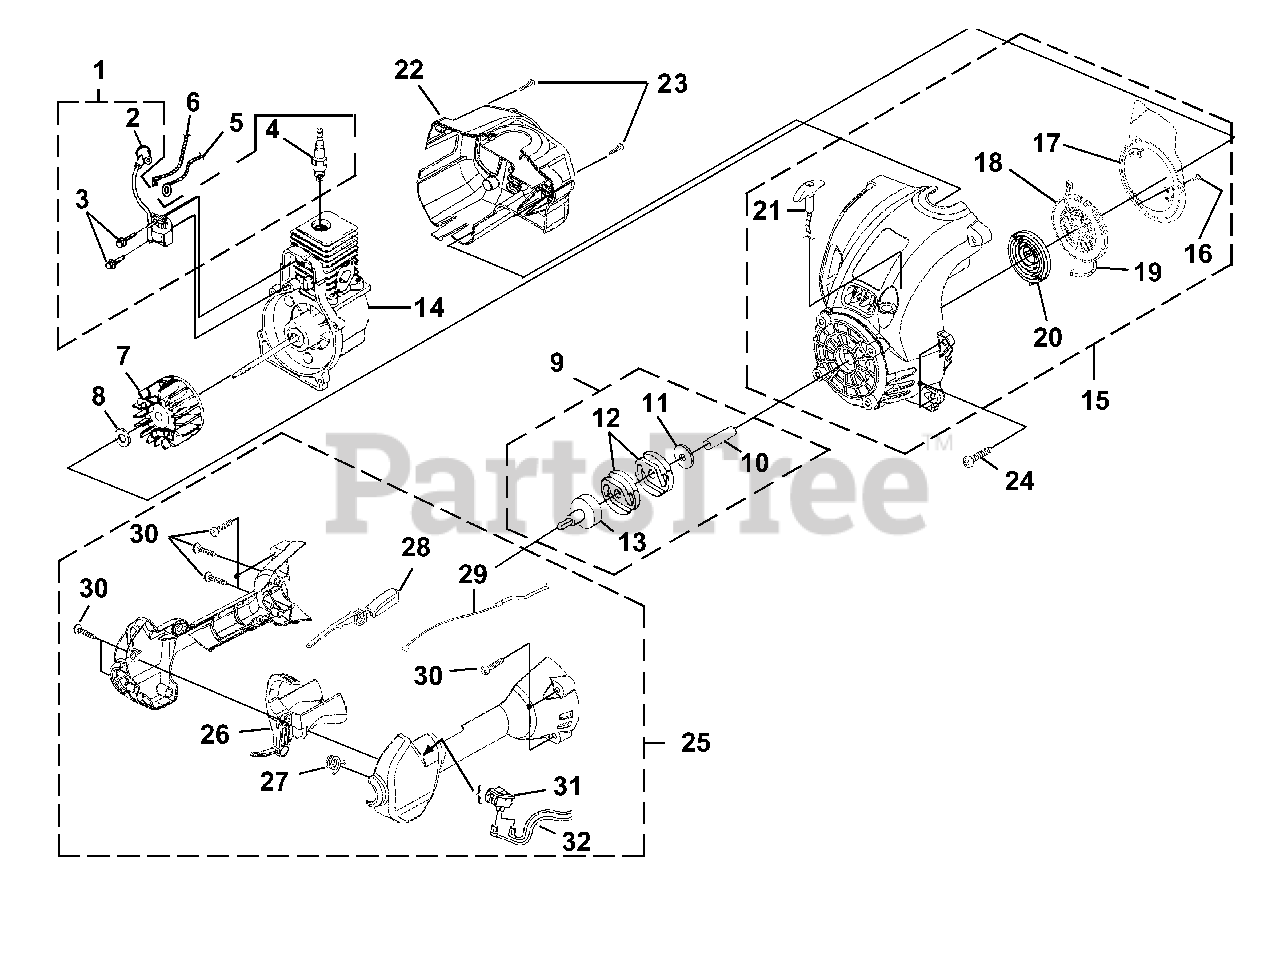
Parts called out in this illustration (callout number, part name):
1	IGNITION KIT
2	TERMINAL & COVER
3	SCREW-Taptite (8-32 X 1")
4	SPARK PLUG
5	LEAD-Electrical
6	LEAD-Electrical
7	ROTOR KIT
8	WASHER-Flat
9	CLUTCH AND DRUM KIT
10	SPACER
11	WASHER-Flat
12	CLUTCH
13	CONNECTOR AND DRUM
14	SHORT BLOCK
15	COMPLETE STARTER ASSEMBLY
16	SCREW-Thread Form (8-16 X 1/2")
17	BAFFLE-Air
18	PULLEY-Starter
19	ROPE-Starter (42")
20	SPRING & CONTAINER
21	GRIP-Starter (Yellow)
22	HOUSING-Rear Kit
23	SCREW-Plastite (10-14 X 7/8")
24	SCREW-Taptite (10-24 X 3/4")
25	CONTROL HANDLE ASSY.
26	TRIGGER-Throttle
27	SPRING
28	THROTTLE INTERLOCK
29	SWITCH
30	SCREW-Taptite (10-14 X 1")
31	CABLE-Throttle
32	LEAD-Electrical
